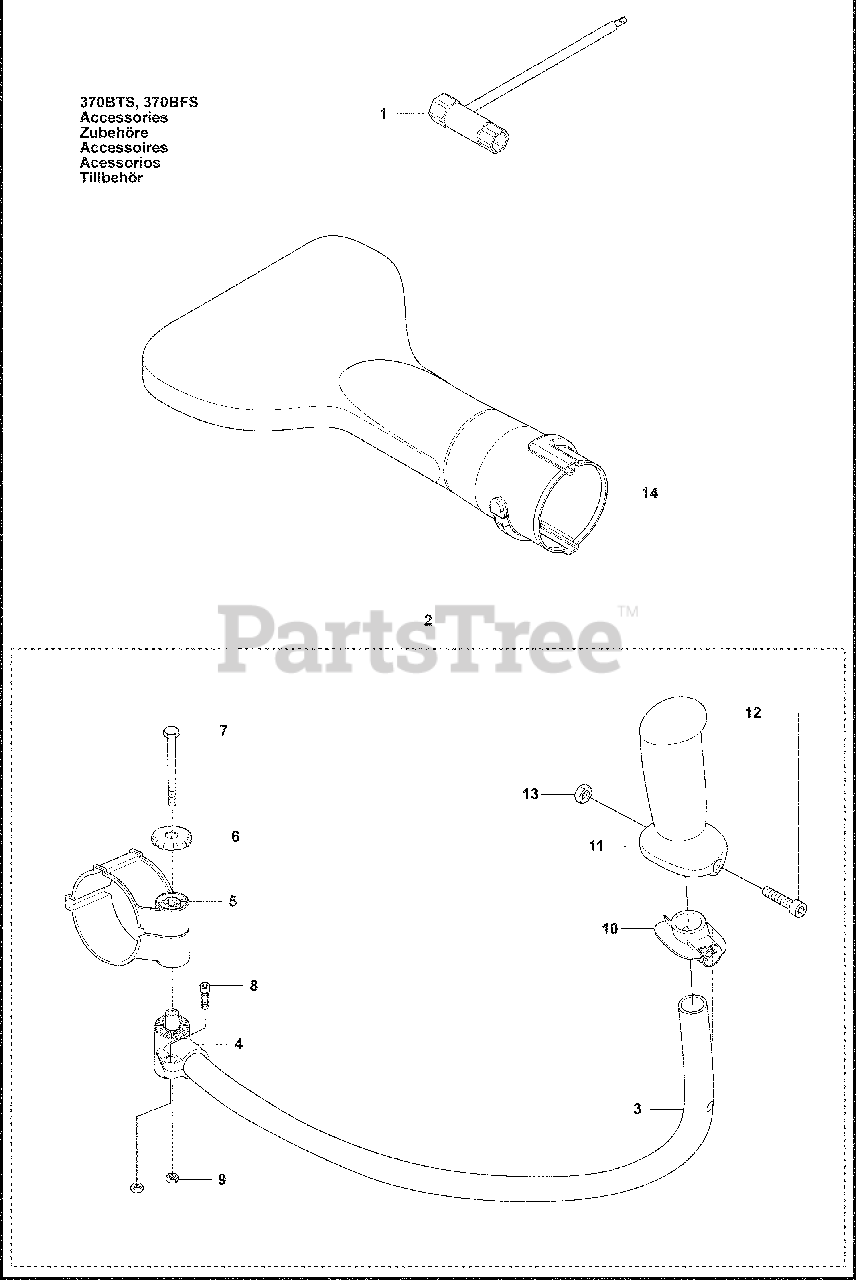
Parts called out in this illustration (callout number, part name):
1	SOCKET
2	Handle, 170 BT
5	HOLDER TH
6	Air Filter Cover Knob
8	Screw, MC6S 5 X 10
9	Hex Nut, M5 X .80 DIN
13	Hex Nut, M5 X .80 DIN
14	Flat Nozzle
